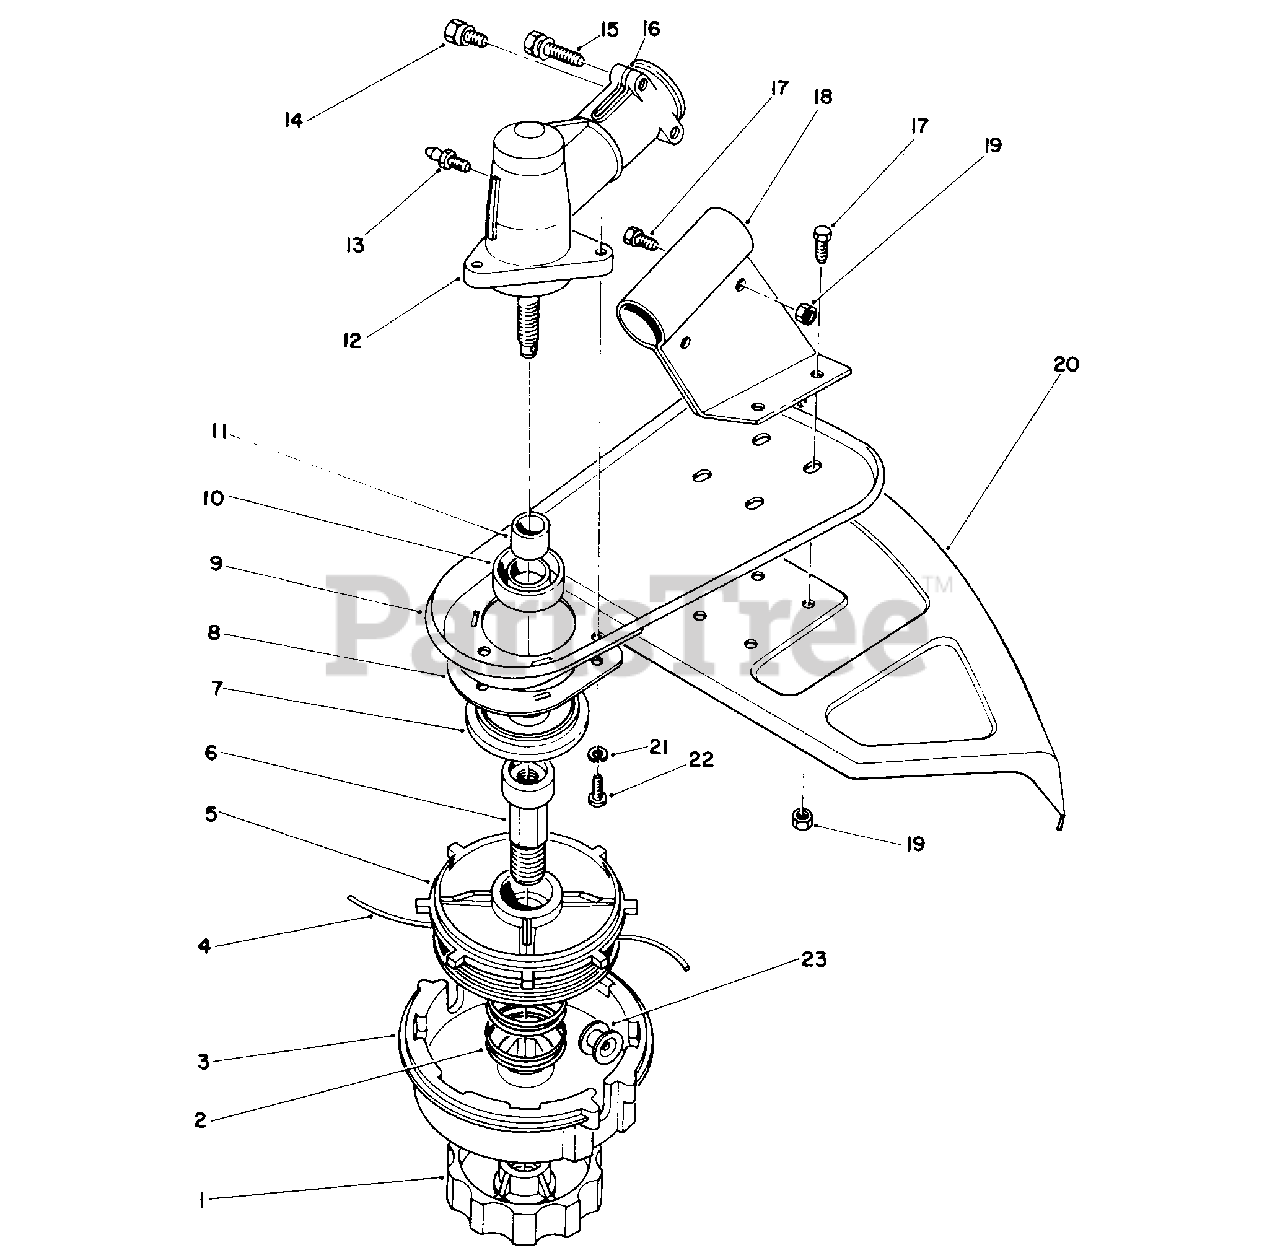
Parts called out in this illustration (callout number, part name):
1	Knob-L.H.
3	Spool-Housing Assembly
4	Line-Cutting .08 Dia. 38'Optional
5	Spool-Inner
7	Cap-Dust
8	Guard-Grass Wrap
9	Support-Shield
10	Seal-Oil
11	Sleeve-Spline
12	Gear Box Assembly (Incl. Ref. #10, 11, & 13-16)
13	Fitting-Grease
14	Screw-Hex. Hd. Cap
15	Screw-Hex. Hd. Cap
16	Washer-Flat
17	Screw-Hex. Hd. Can
18	Bracket-Shield
19	Nut-Lock
20	Shield-Grass
21	Washer-Lock
22	Screw-Guard
